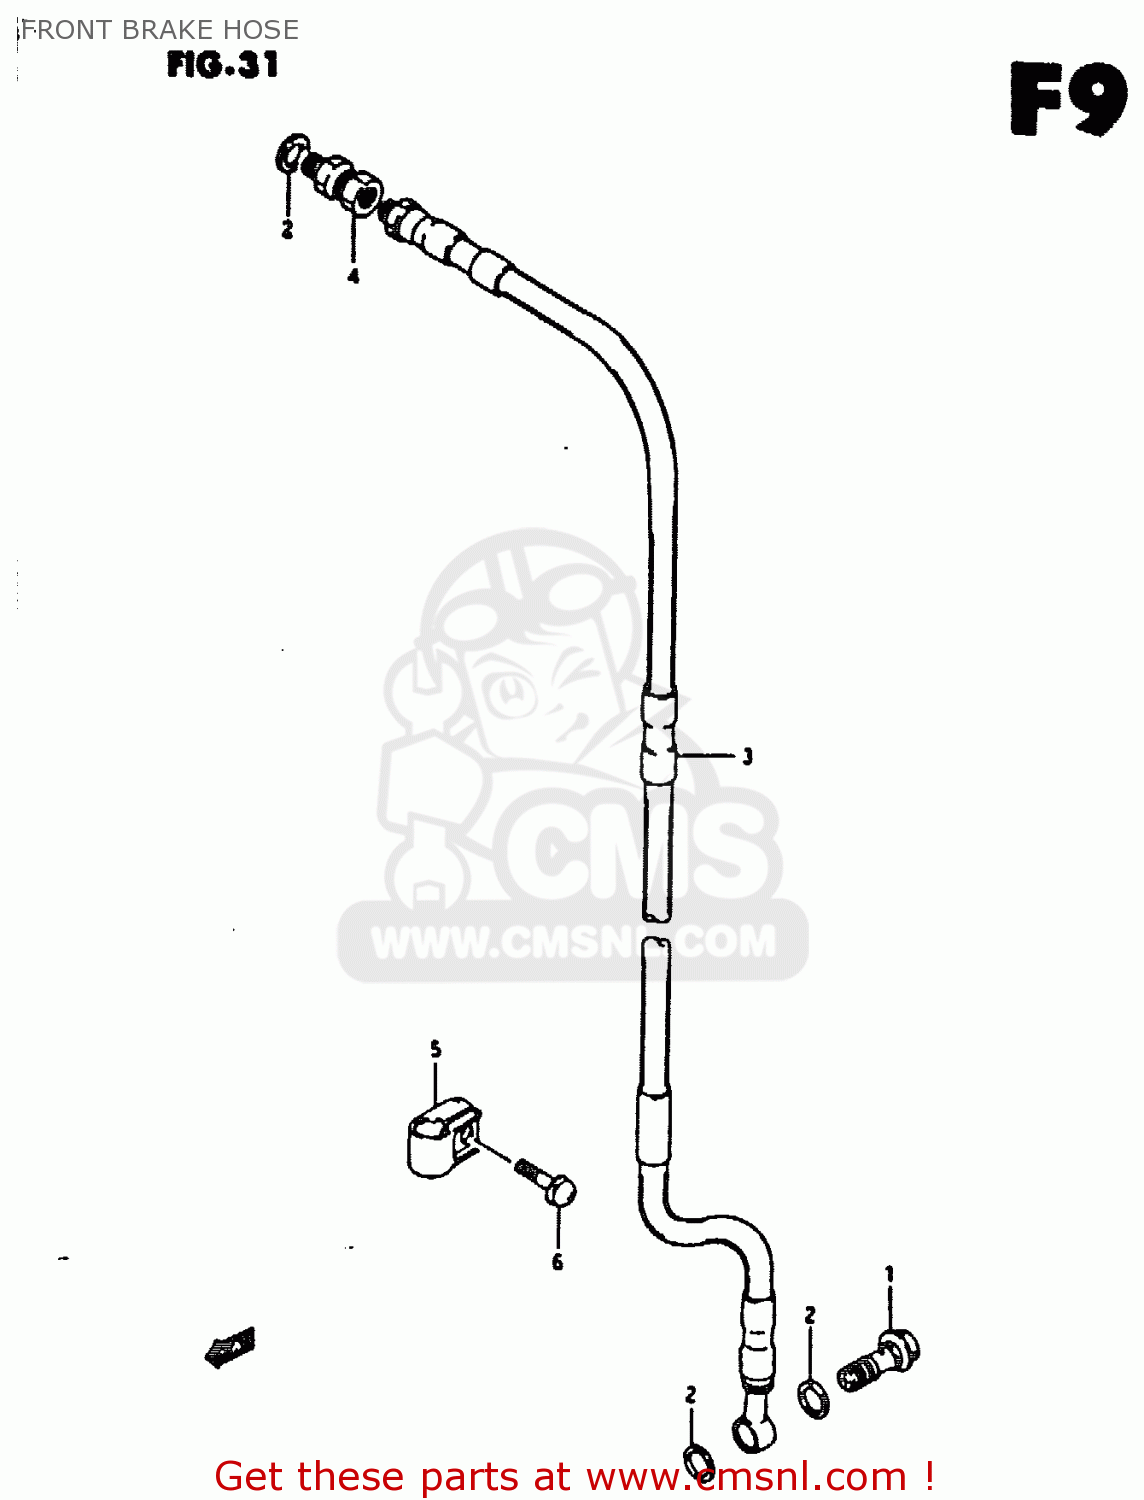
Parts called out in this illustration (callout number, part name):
1	BOLT UNION
2	WASHER(10X15X1.5)
3	HOSE,FR BRAKE
4	ADAPTOR,BRAKE HOSE
5	CLAMP,FRONT BRAKE HOSE
6	SCREW
